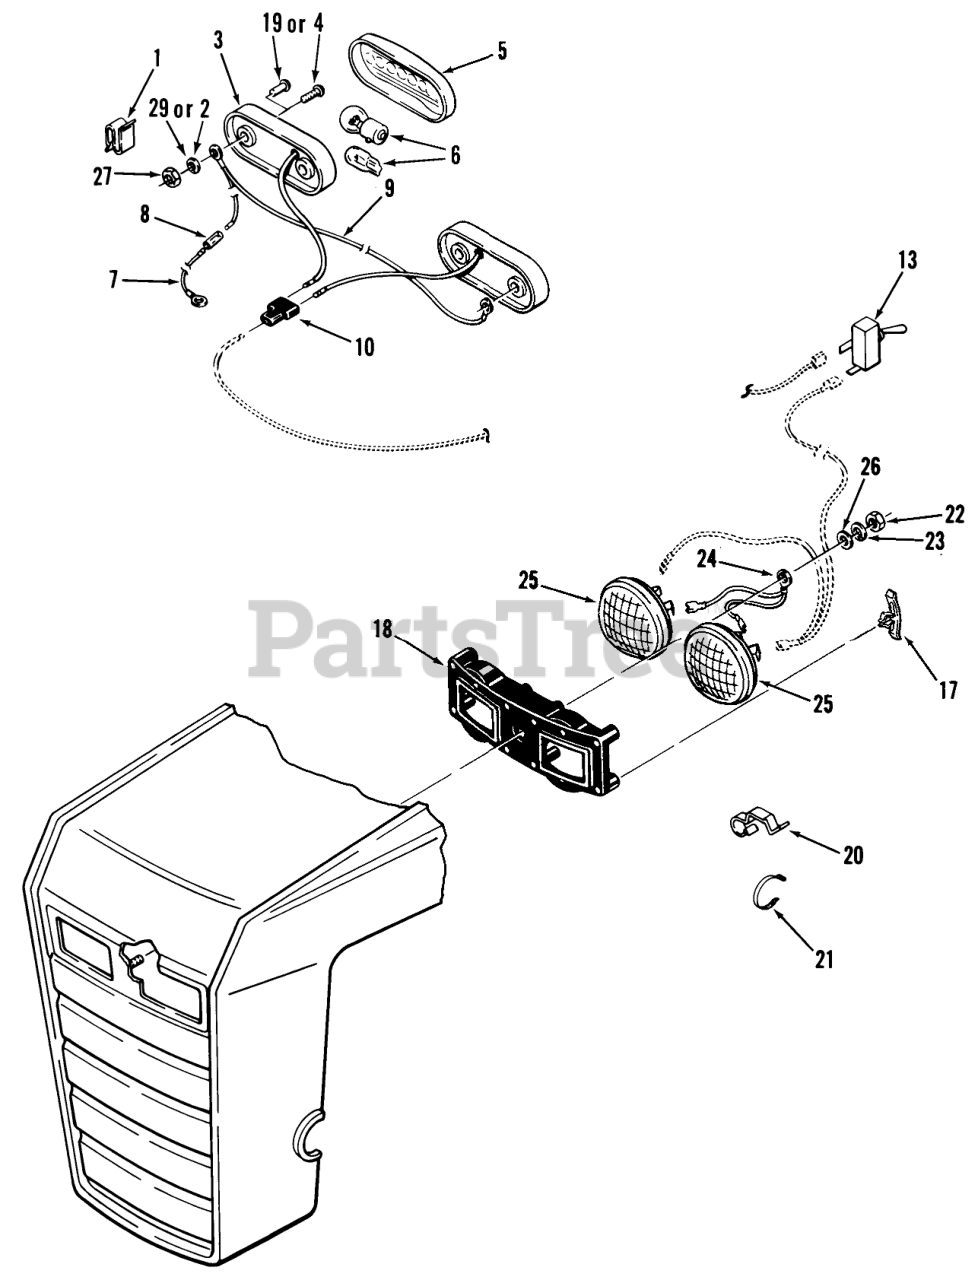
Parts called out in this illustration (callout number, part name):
1	SPEED CLIP
2	Lockwasher
3	BASE-TAIL LIGHT
4	Screw
5	Lens-Taillight
6	Bulb
6	LIGHT BULB
7	ASSEMBLY-WIRE
8	CONNECTOR 2 WIRE
9	Taillight Wire
10	CONNECTOR 3 WIRE
13	SWITCH-LIGHTS
17	CLIP-SPRING
18	Headlight Retainer
19	Poprivet
20	CLIP-WIRE
21	PLASTIC TIE
22	Nut
23	Washer-Lock
24	LIGHT GROUND WIRE
25	HEADLAMP
26	WASHER 5/16 SAE
27	Nut
28	WASHER
